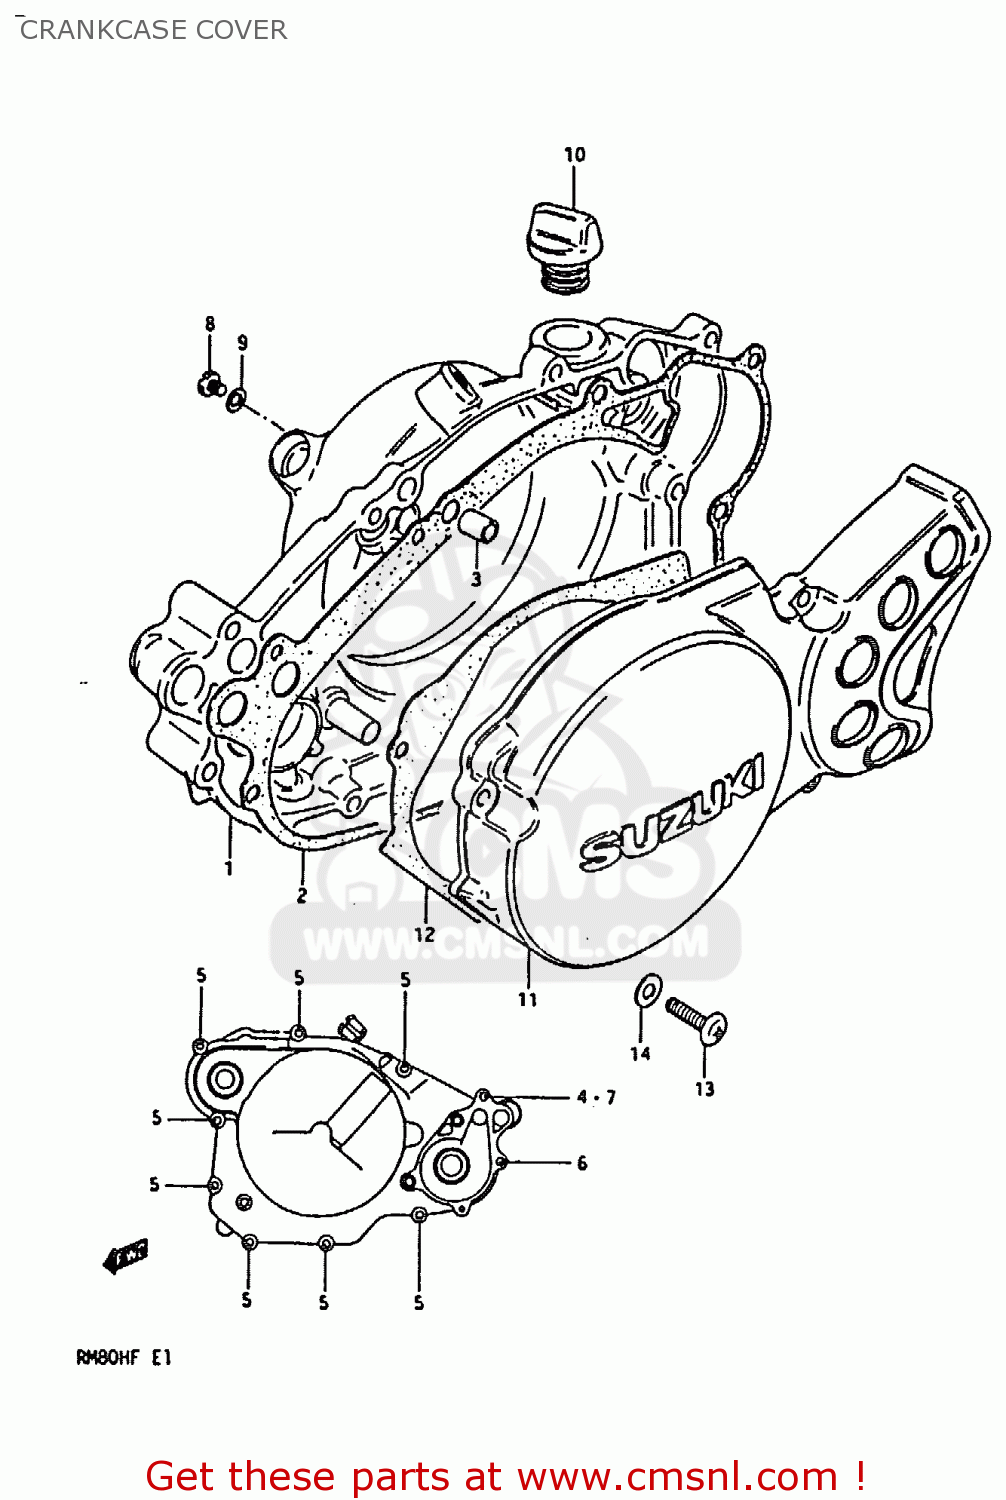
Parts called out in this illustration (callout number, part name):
1	COVER,CLUTCH
2	GASKET,CLUTCH COVER (MCA)
3	PIN
4	WASHER
5	SCREW
6	SCREW
7	SCREW
8	SCREW(6X10)
9	GASKET(6.2X11X1) (NAS)
10	PLUG
11	COVER,MAGNETO
12	GASKET,MAGNETO COVER (NAS)
13	SCREW 5X20
14	WASHER,5MM
